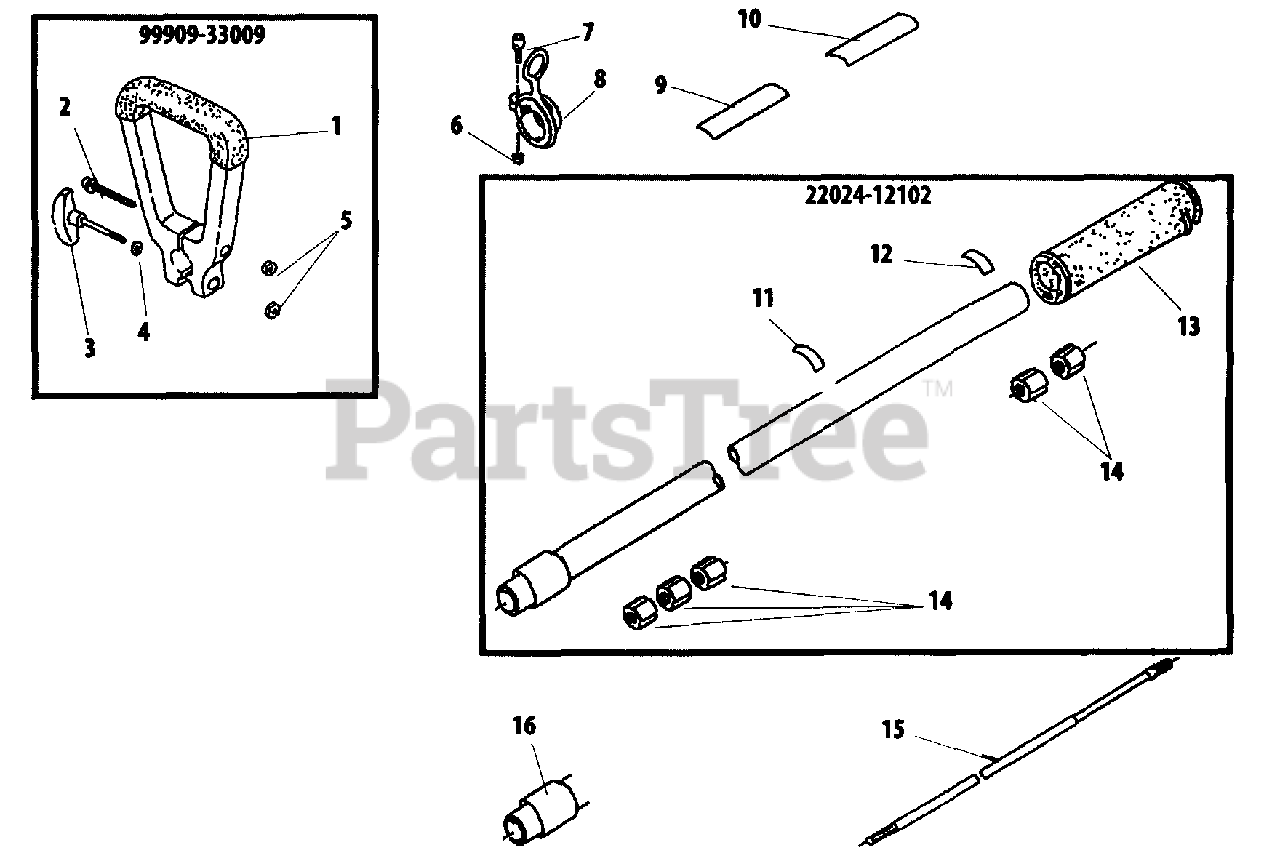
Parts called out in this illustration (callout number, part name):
1	HANDLE - FRONT
2	SCREW
3	THUMBSCREW
4	WASHER
5	NUT - 6
7	SCREW - 5X12
8	HANGER
9	LABEL
10	LABEL - CAUTION
11	LABEL - ALIGNMENT
12	LABEL - HANDLE LOCATION
13	GRIP
14	BUSHING
15	PIPE, MAIN
16	CAP, MAIN PIPE
